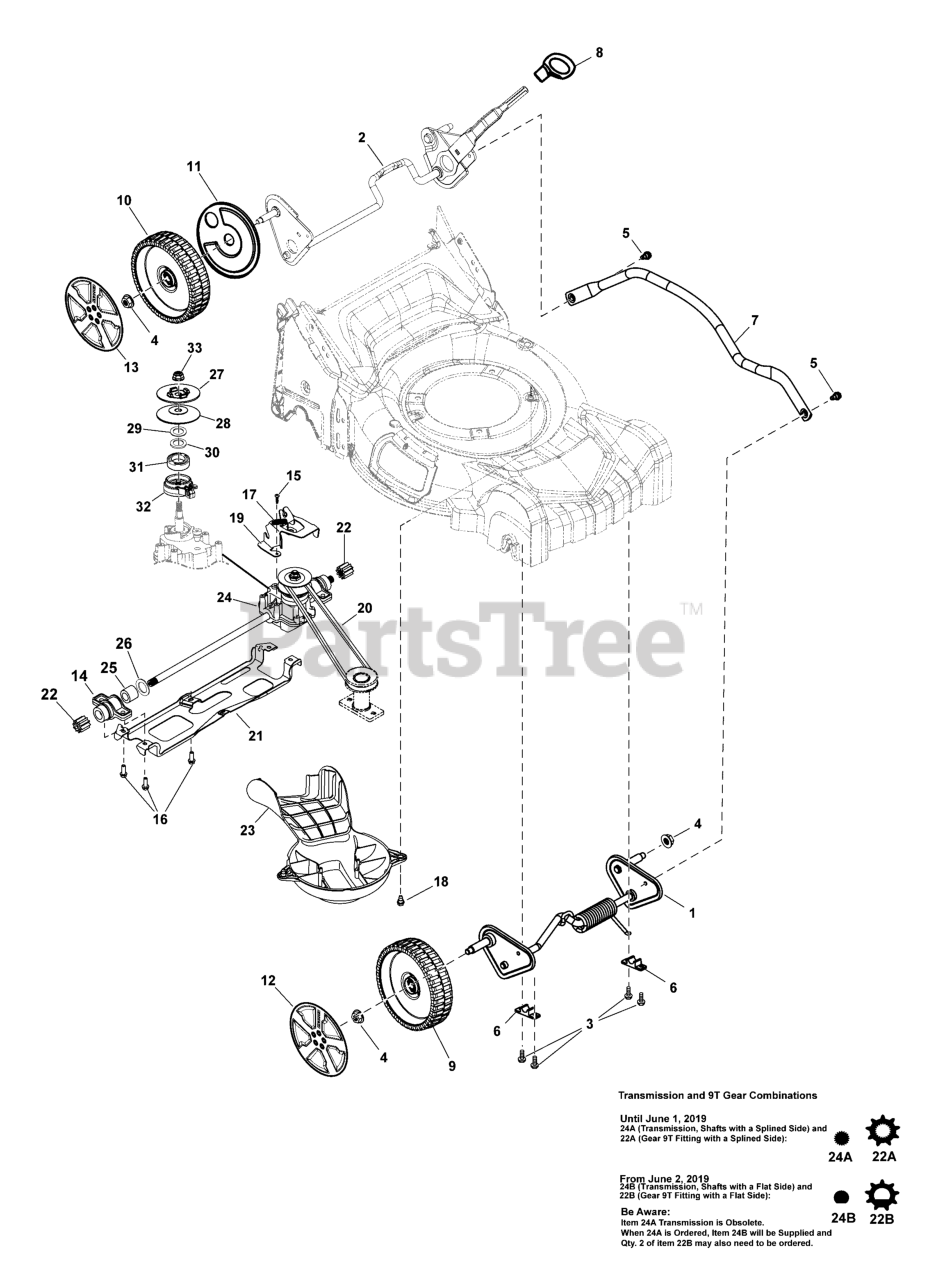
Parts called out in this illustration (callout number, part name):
1	AXLE, Front
2	AXLE, Rear
3	SCREW, 1/4-15X3/4, Self-Tapping, BZ
4	NUT, Hex Flange, Nylock, 3/8-16
5	SCREW, 1/4-20 x 1/2
6	BUSHING, Lock
8	KNOB, Red
8	KNOB, Black
9	WHEEL, 200 x 49
10	WHEEL, Drive
11	DUST COVER, Wheel
12	HUBCAP, Front
13	HUBCAP, Rear
14	BEARING ASSEMBLY
15	SCREW, Hex Washer Head, .159 x .43
16	SCREW, 1/4-15 x 1-1/4
18	SCREW, 1/4-20 x 1/2
19	BRACKET
21	SUPPORT
22A	GEAR, 9 Tooth
22B	GEAR, 9 Tooth
23	COVER, Rear
24A	TRANSMISSION
24B	TRANSMISSION
27	PULLEY HALF, Upper
28	PULLEY HALF, Lower
29	SHIM, 20
30	SHIM, 10
31	BEARING
32	CAM PULLEY, Speed
33	NUT, Lock
